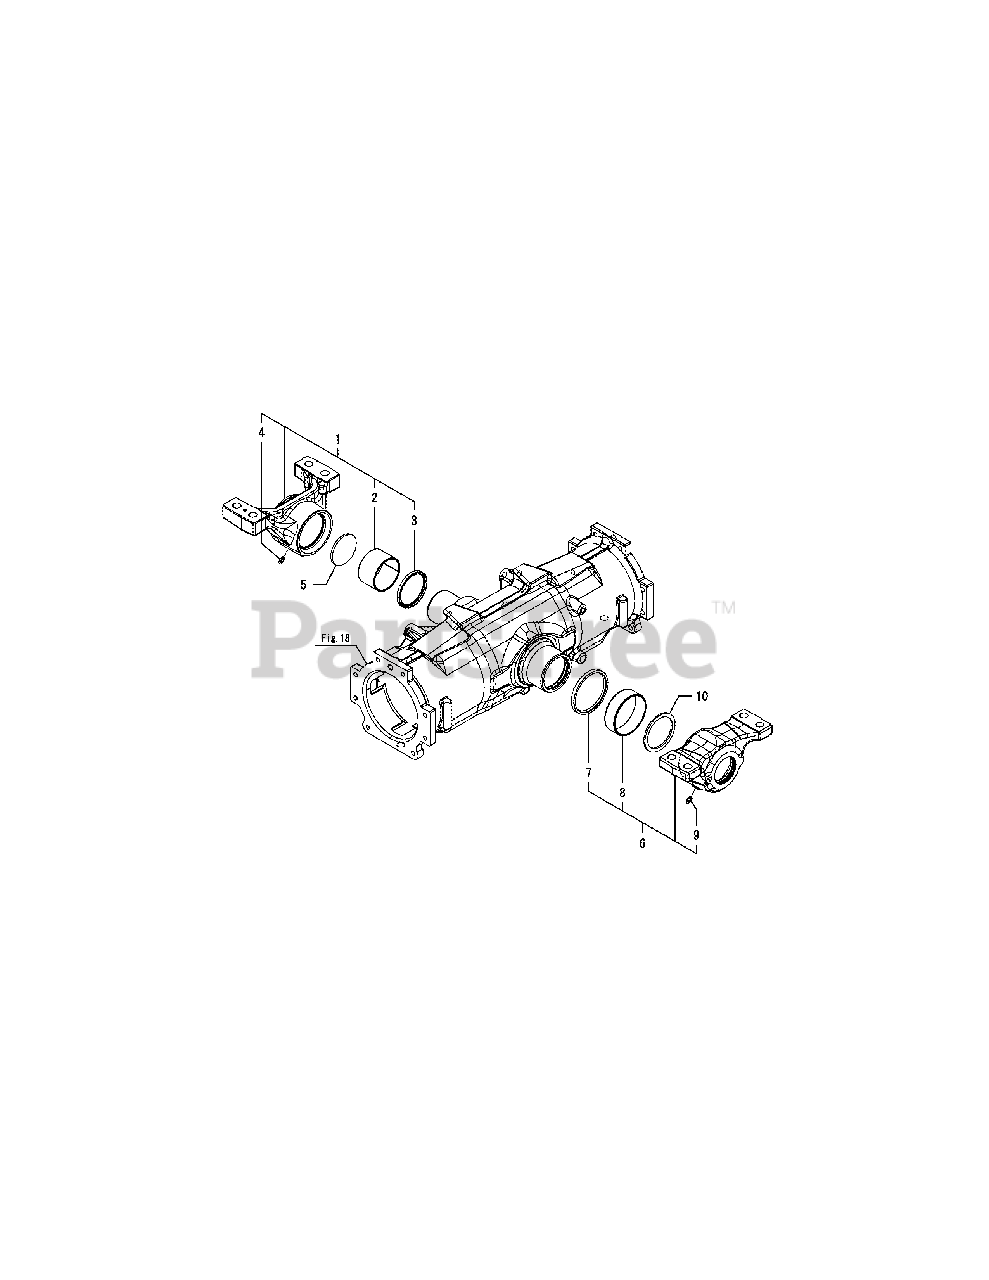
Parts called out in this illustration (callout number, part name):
1	SUPPORT ASSY, FRONT F
2	BUSH, 60X65X40
3	SEAL, VB607005
4	NIPPLE M6F, GREASE
6	SUPPORT ASSY, FRONT R
7	SEAL VB75 85 6.5, OIL
9	NIPPLE M6F, GREASE
10	WASHER 62X75X3
